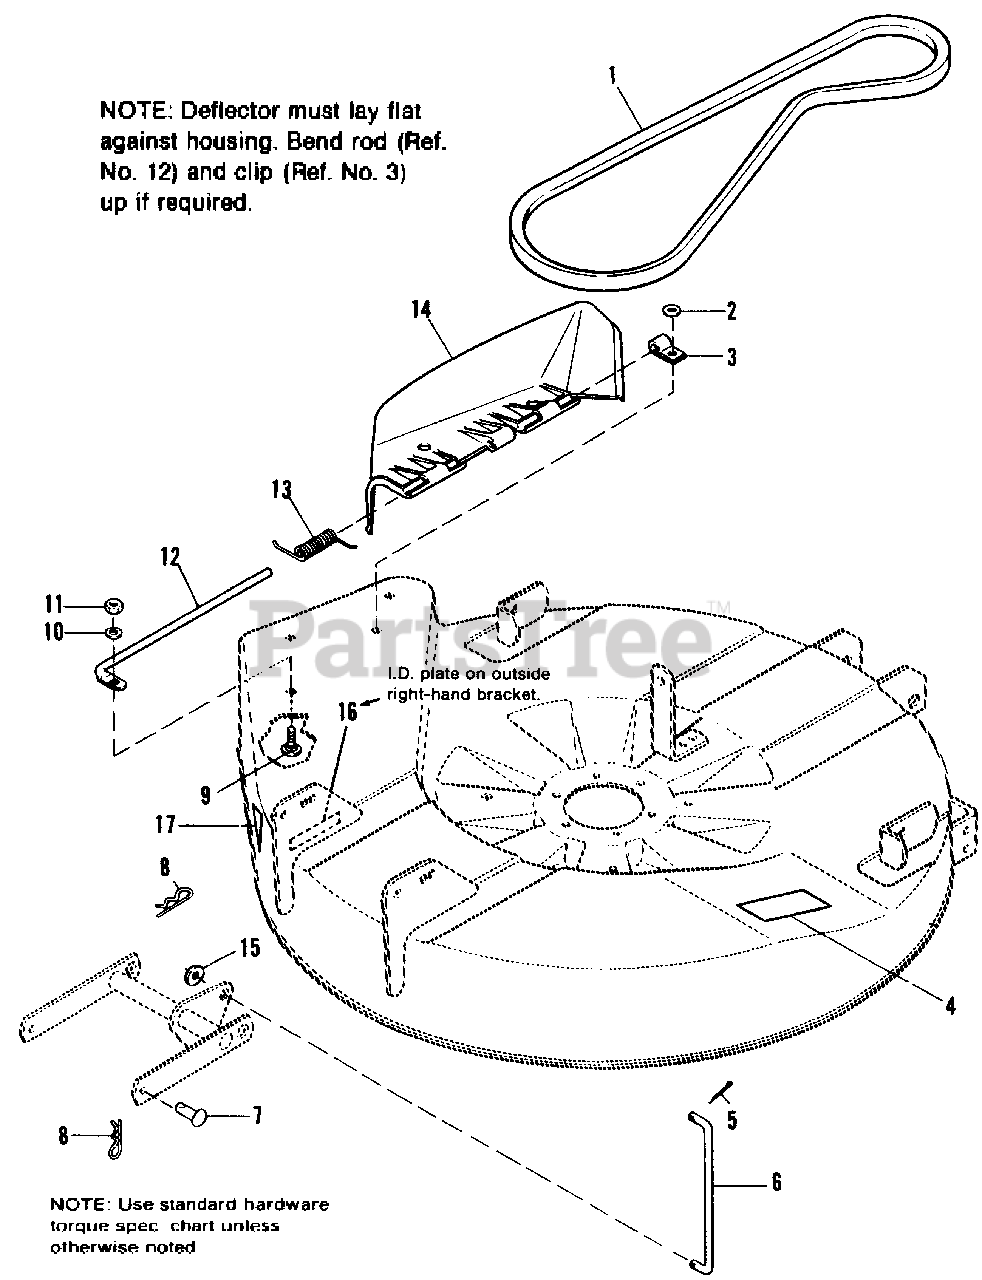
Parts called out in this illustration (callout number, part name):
1	V-BELT (30" Mower Only)
1	V-BELT (26" Mower Only)
2	WASHER, Plain, 3/16
3	CLIP, 5/16
4	DECAL, Danger
5	PIN, Cotter, 3/32 x 1
8	CLIP, Hairpin
9	BOLT, Carriage, 1/4-20 x 3/4
10	LOCKWASHER, 1/4
11	NUT, Hex, 1/4-20
12	ROD, Deflector, Front
15	WASHER, Plain, 3/8
16	PLATE, I.D. (30" Mower)
16	PLATE, I.D. (26" Mower)
17	DECAL, OPEI
